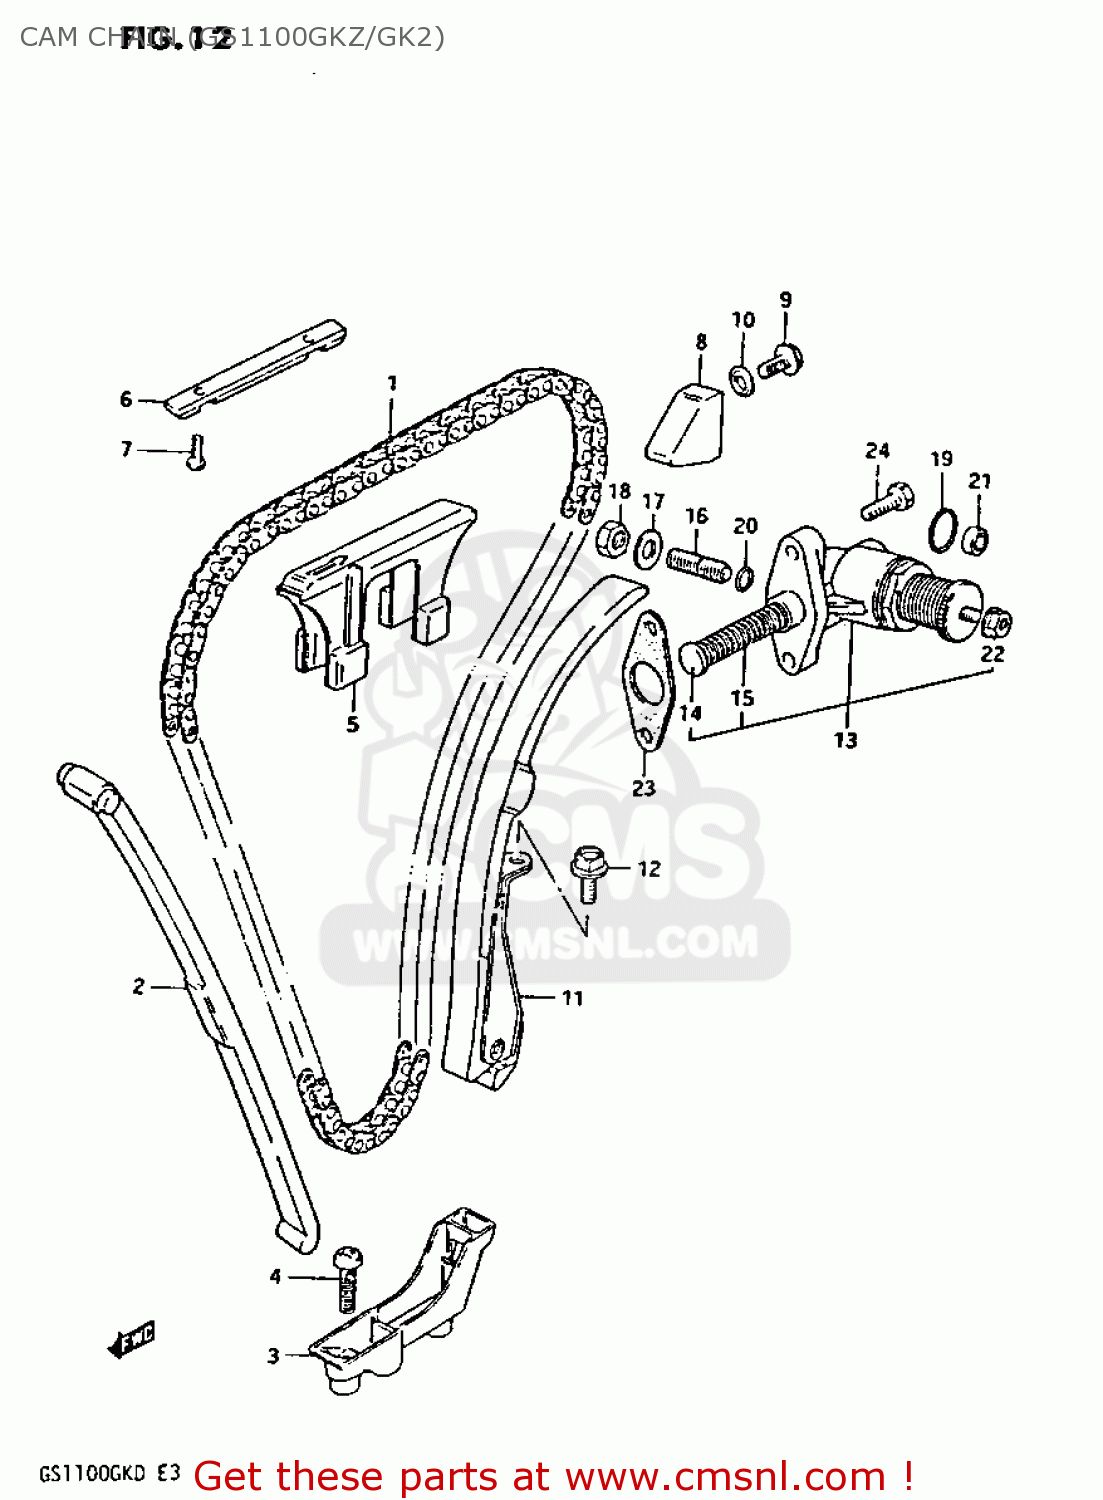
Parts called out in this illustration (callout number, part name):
1	CHAIN,CAMSHAFT DRIVE
2	GUIDE,CAM CHAIN NO.1
3	HOLDER,CAM CHAIN GUIDE
4	SCREW
5	GUIDE,CAM CHAIN NO.2
6	GUIDE,CAM CHAIN
7	SCREW
8	GUIDE,CAM CHAIN
9	BOLT 6X12
10	GASKET(5.8X13X1.2) (NAS)
11	TENSIONER,CAM CHAIN
12	BOLT 8X16
13	ADJUSTER,CAM CHAIN TENSIONER
14	ROD,PUSH
15	SPRING
16	SCREW
17	WASHER
18	NUT
19	O RING(D:2.4,ID:20.8)
20	O RING(D:1.9,ID:5.7)
21	SEAL,OIL(10X16X4)
22	NUT
23	GASKET,TENSIONER ADJUSTER (MCA)
24	SCREW (6X25)
